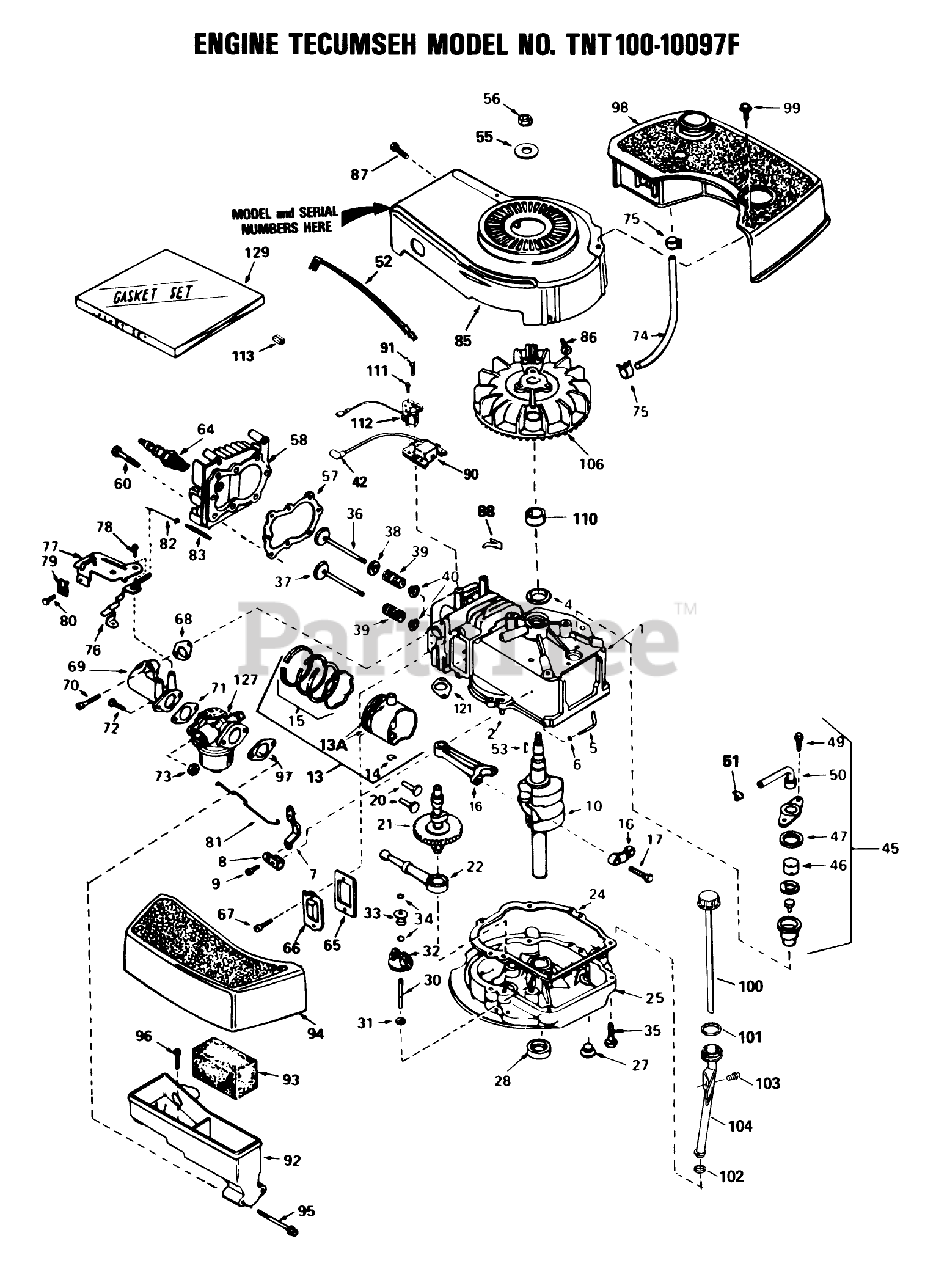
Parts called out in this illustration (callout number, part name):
1	Cylinder Assy. (Inc. #2 4)
2	Pin-Dowel
4	Seal-Oil
5	Rod, Governor (Incl. No. 36)
6	Washer-Flat
7	Governor Lever
8	Clamp-Lever, Governor
9	Screw
10	Crankshaft
13	Piston-Pin Ring Assy. (Std.)(Incl. Ref. #16A, 17 18)
13	Piston-Pin Ring Assembly (.010 oversize)(Incl. Ref. #16A, 17 18)
13	Piston, Pin Ring Assy. (.020 Oversize)(Incl. Ref. #13A, 14, 15)
13A	Piston Pin Assy. (Std.)(Incl. Ref. #14)
13A	Piston Pin Assembly (.010 oversize)(Incl. Ref. #18)
13A	Piston Pin Assy. (.020 Oversize) (Incl. Ref. #14)
14	Ring-Retaining, Piston Pin
15	Ring Set-Piston (Std.)
15	Ring Set, Piston(.0100versize)
15	Ring Set (.020" OS)
16	Rod Assy., Connecting (Incl. Ref. #17)
17	Bolt-Rod, Connecting
20	Lifter-Valve
21	Camshaft(Mech.Comp. Release)
22	Oil Pump ASM
24	Gasket
25	Flange Assy.-Mounting (Incl. Ref. #26, 27, 28 31)
27	Plug Oil Drain
28	Seal Oil
30	Shaft-Governor
31	Washer-Flat
32	Governor Gear ASM
33	Spool-Governor
34	Ring-Retaining
35	Screw (1/4-20 x 1-1/4)
36	Valve, Intake (Std.) (Incl. Ref. #40)
36	Valve, Intake (1/32" oversize)(Incl. No. 40)
37	Valve, Exhaust (Std.)(Incl. No. 40)
37	Valve, Intake (1/32" oversize)(Incl. No. 40)
38	Seal Assy., Intake
39	Spring-Valve
40	Cap-Valve, Spring
42	Cover-Spark Plug
45	Breather Assy. (Incl. Ref. #46 thru 51)
46	Element-Breather
47	Gasket-Breather
49	Screw (10-24 x 9/16)
50	Tube, Breaker
51	Clip, Breather
52	Wire-Ground
53	Key-Flywheel
55	Washer-Belleville
56	Nut-Flywheel
57	63573 GIL 42 SNWTHW
58	Head-Cylinder
60	Screw (5/16-18x1-1/2)
64	Spark Plug-Resistor (R J19 L M)
65	Gasket-Breather
66	Cover-Valve
67	Screw
68	Gasket-Intake
69	Pipe, Intake (Incl. No. 68)
70	Screw (1/4-20 x 1)
71	Gasket-Carburetor
73	Nut and Lock Washer (1/4-28)
74	Line-Fuel
75	Clamp-Line, Fuel
76	Lever Control
77	Control Assy., Speed (Incl. Nos, 76, 78 89)
78	Screw, Hex Washer Hd Shoulder Self-Tap
79	Conduit
80	Screw (10-32 x 3/8)
81	Link-Throttle
82	Link Governor Spring
83	Spring Governor
85	Housing-Blower
86	Screw (1/4-20x19/32)
87	Screw (10-24 x 9/16)
88	Clip-Wire
90	Solid State
91	Screw
92	Body Air Cleaner
93	Filer, Air
94	Cove, Air Cleaner
95	Screw Fil Hd.
96	Screw, Hex Washer Hd Shoulder Self-Tap
97	Gasket-Air Cleaner
98	Tank-Fuel
99	Screw (10-32 x 35/64)
100	Dipstick, Oil
101	O-Ring
102	Gasket
103	Screw (10-32 x 1/2)
104	Tube, Oil Fill
106	Flywheel
110	Spacer
111	Screw (8-32x27/64)
112	Coil, Alternator
113	Connector-Body
121	Gasket Exhaust
127	Carburetor (Incl. Ref. #71)
129	Gasket Set
